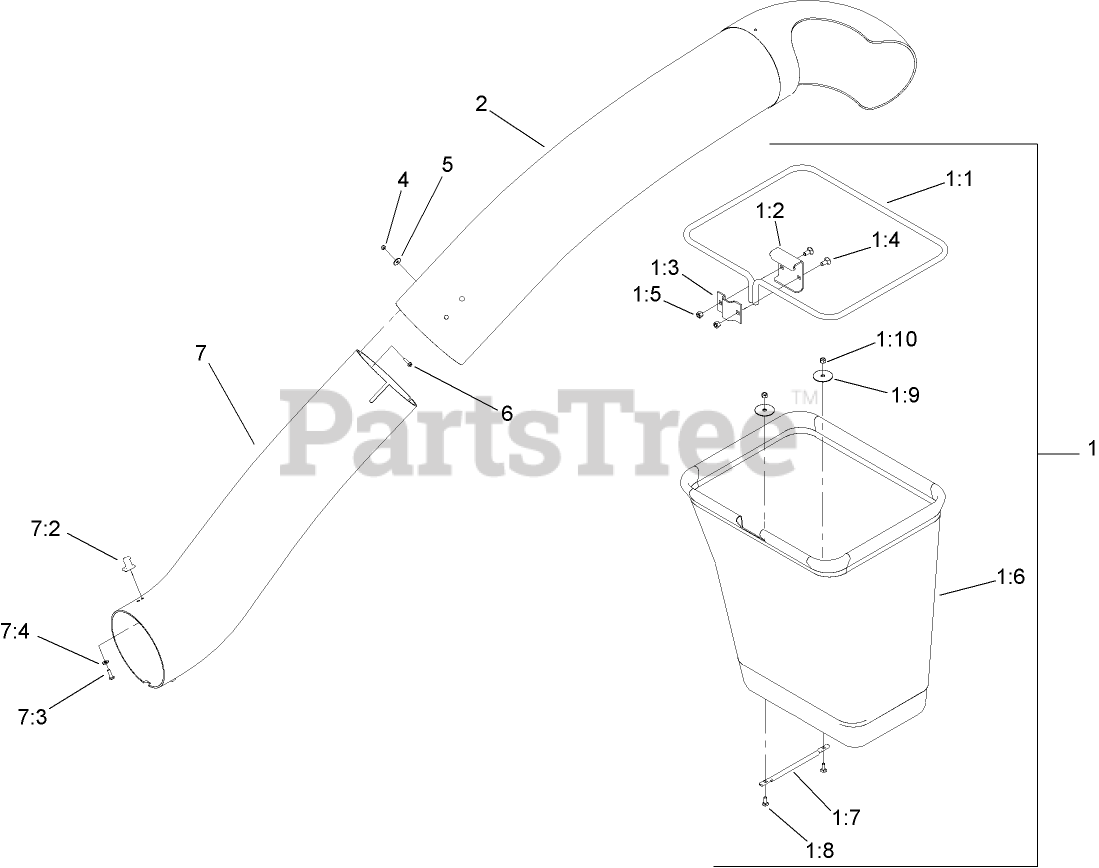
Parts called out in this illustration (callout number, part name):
1	BAG ASM
1:1	FRAME-BAG
1:2	HANGER-BAG
1:4	BOLT-CARR
1:5	NUT-LOCK, NI
1:6	BAG-CLOTH
1:7	HANDLE-BAG
1:8	BOLT-CARR
1:9	WASHER
1:10	NUT-LOCK, NI
2	TUBE-UPPER
4	NUT-LOCK, NI
5	WASHER-FLAT
6	SCREW-HWH
7	LOWER TUBE ASM
7:2	LATCH-KEEPER
7:3	SCREW-PPH
7:4	WASHER-FLAT
